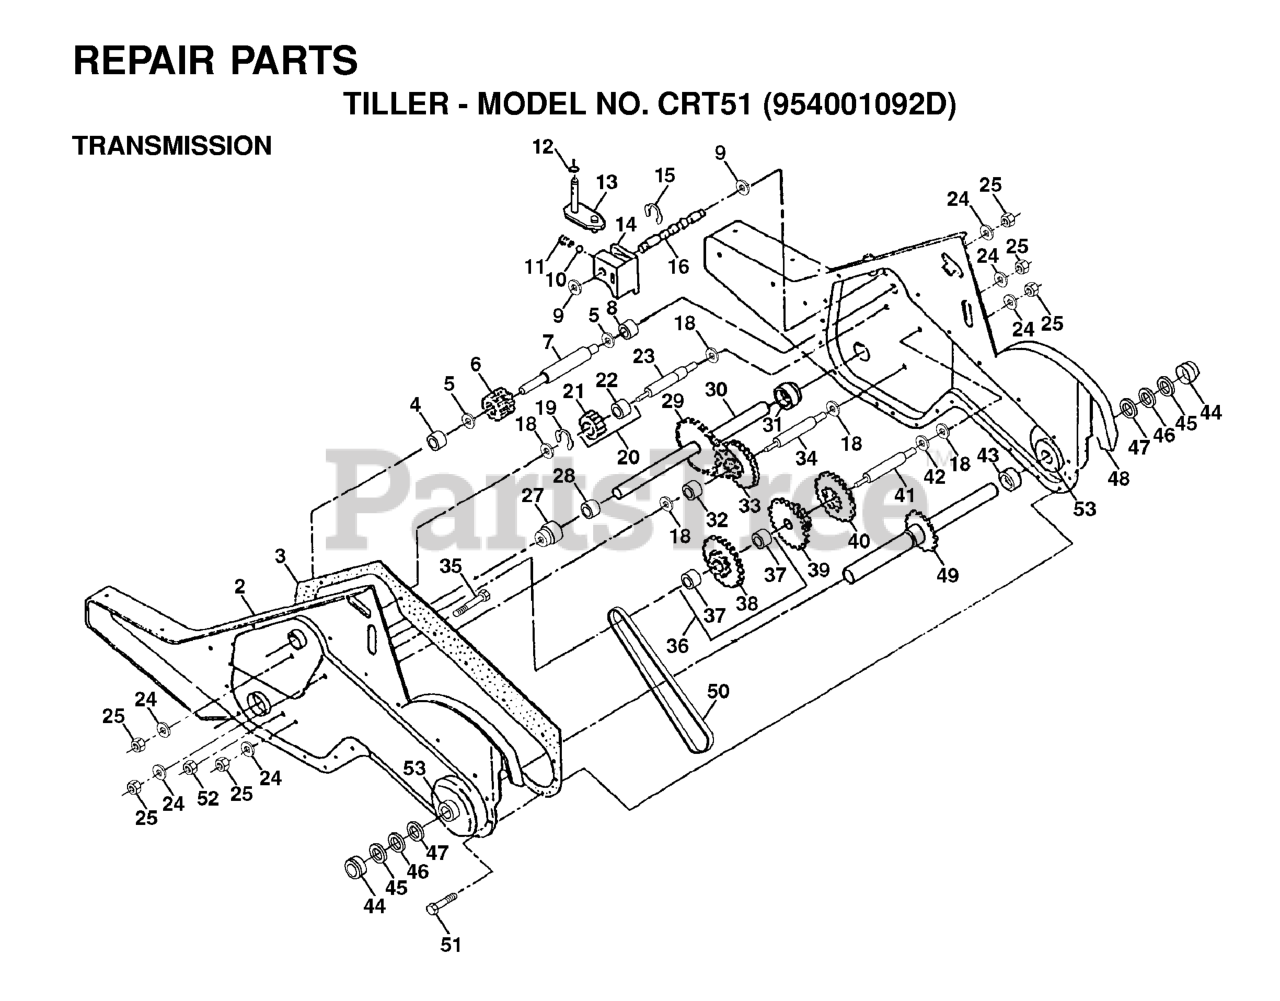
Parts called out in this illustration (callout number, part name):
1	TRANSMISSION ASSY
2	GEARCASE LH W/BRG
3	GASKET TI
4	NEEDLE BRNG LT
5	THRUST WASHER
6	GEAR.PINION.INPUT
7	SHAFT.INPUT."D".TILLER
8	BEARING TI
9	WASHER, SEAL (2 2)
10	STEEL BALL KIT
11	SPRING-SHIFT CRT
13	BRACKET ASM.SHIFT.CRT
14	SHIFT FORK TI
16	SHAFT.SHIFTER.TILLER
20	GEAR ASSY CRT
21	GEAR-REV IDLR CRT
22	NEEDLE BEARING TI
24	LOCKWASHER
25	NUT.ASF.HEX.7/16
27	BEARING, SHAFT LH CRT
30	GROUND SHAFT ASS'Y
31	BEARING, SHAFT RH CRT
33	SPRCKT 8 GEAR CRT
34	SHAFT.SECONDARY.REDUCTION.CRT
35	SCRW WHIZ LOK CRT
36	SPROCKET.ASM.W/BEARING.TILLER
37	BEARING
38	SPROCKET, TINE
41	SHAFT.REDUCTION.TILLER
42	BRNG RACE T
44	CUP
45	RING.SPIRAL.CRT.TILLER
47	OIL SEAL STD
48	GEARCASE RH W/BRG
49	TINE SHAFT
50	CHAIN.TILLER
51	SCREW
53	BEARING KIT
